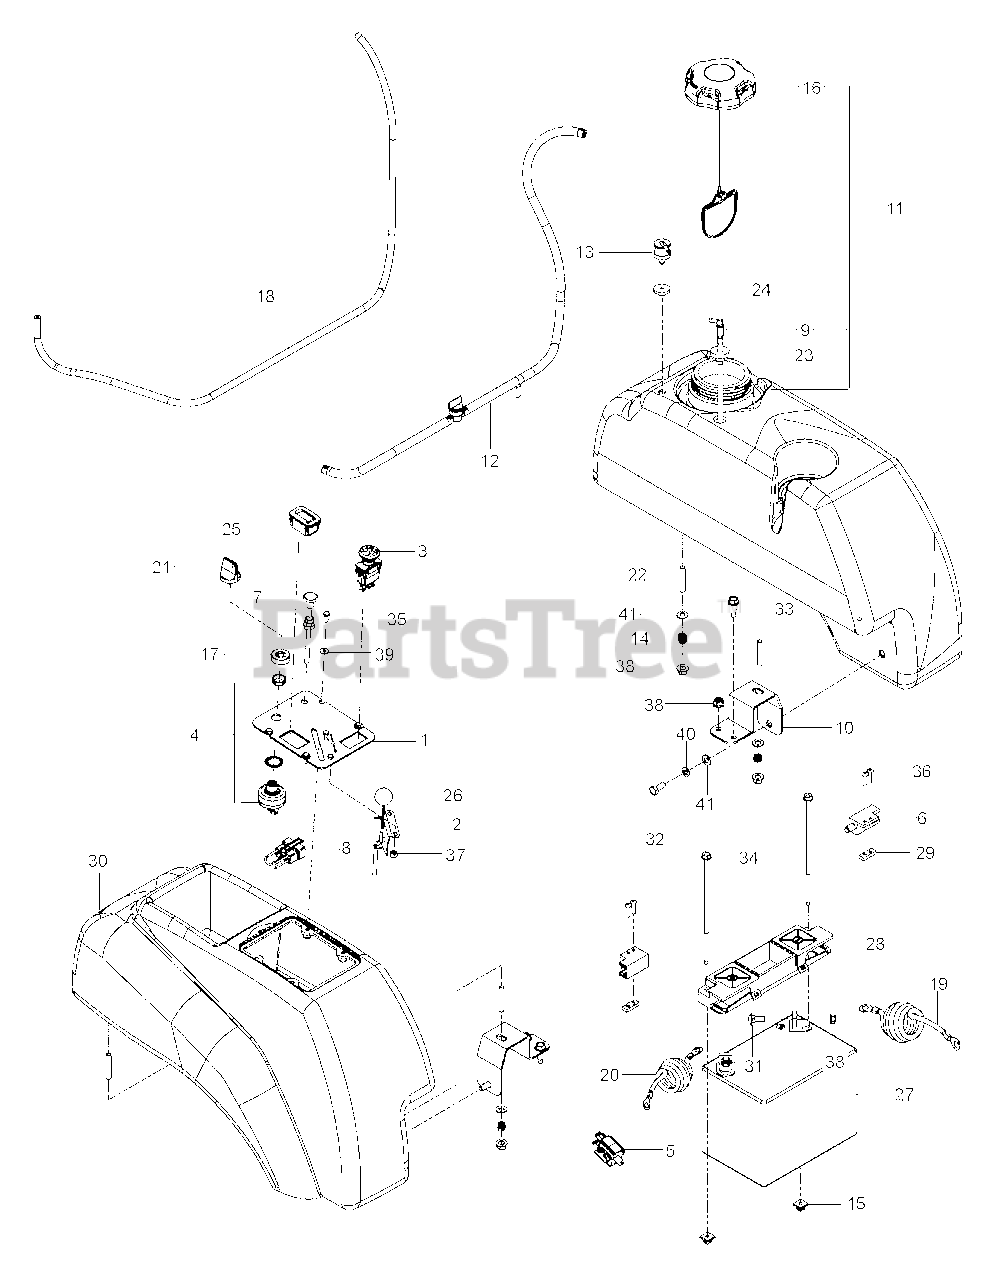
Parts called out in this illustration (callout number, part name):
1	PLATE.CONSOLE.BLACK
2	THROTTLE CONTROL W/BALL KNOB
3	SWITCH, PTO 10 AMP
4	SWITCH, IGNITION, INDAK
5	SWITCH, BRAKE 3P
6	SWITCH INTERLOCKT
7	CABLE, CHOKE
8	PLUG, TIMER
9	FITTING, FUEL
10	SUPPORT, TANK, BLK
11	TANK FUEL LT ASM MZ GRAY
12	FUEL.HOSE.SHUT.OFF.ASM.10".26"
13	VALVE.FUEL.CHECK
15	PUSH NUT-NYLON
16	CAP, FUEL
17	CAP IGNITION NUT
18	HOSE, FUEL .25 ID X 26"
19	NEG. CABLE, 28"
20	POST.CABLE LONG
21	KEY, IGNITION
22	STUD, 5/16C
23	RUBBER GROMMET
24	GROMMET, CHECK VALVE
25	RP GUAGE.SRVCMNDR.HRMTR.
26	KNOB.ROUND.BALL.BLACK
27	BATTERY, 12 V 330 AMP
28	BATTERY HOLD DOWN
29	TAPPED PLATE
30	FENDER CONSOLE
31	BOLT 5/16C X 3/4" CARRIAGE
32	HCS 5/16C X 3/4
33	RP BLT 5/16-18 X 1 THRD FORM D
34	Bolt, 1/4-20 X 7.5
35	HCS #10-24 X 1/2
36	SCR #10-24 X .75 SKT HD BLK
37	NUT 10-24 NYLOC
38	5/16-18 NYLOC FLANGE NUT
39	WASHER #10
40	WASHER 5/16 LOCK
41	FLAT WASHER 5/16 SAE
